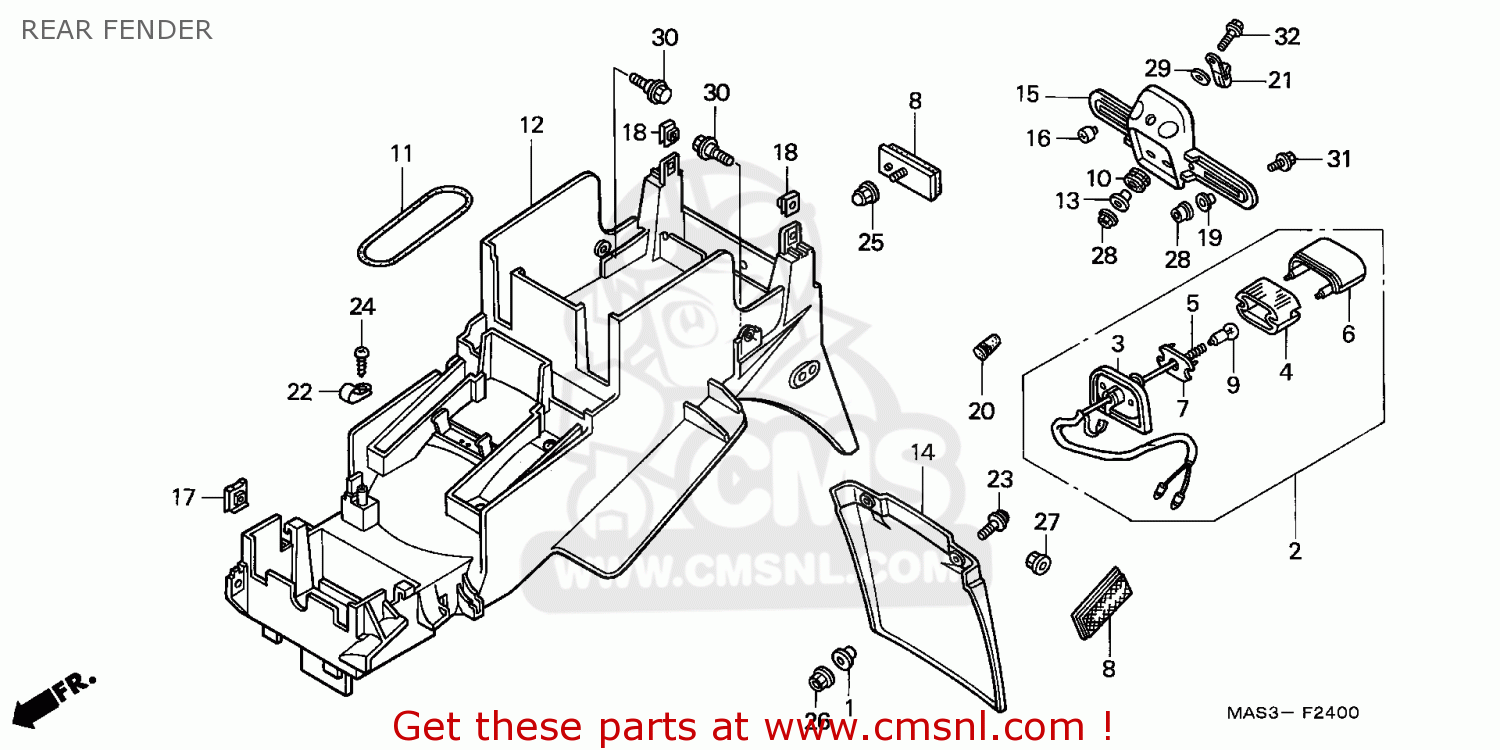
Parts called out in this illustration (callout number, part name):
2	LIGHT ASSY.,LICEN
3	BASE COMP.
4	LENS LICENSE
5	WIRE, LICENSE LIGHT
6	COVER LICENSE
7	PACKING.LENS
8	REFLECTOR,REFLEX
9	BULB
10	RUBBER,FR-FEND.MT
11	BAND,FR NO PLATE
12	FENDER,REAR
13	COLLAR,RR.FENDER
15	BRKT,NUMBER PLATE
16	NUT,SPECIAL,6MM
17	NUT,CLIP,6MM
18	NUT,CLIP,6MM
19	WASHER,6X20.
20	PLUG,CORN
21	CLIP
22	CLIP WIRE HARN
24	SCREW,TAPPING,(PO)4X
25	NUT,HEX,CAP,5MM
27	NUT,FLANGE,5MM
29	WASHER,PLAIN,6MM
30	BOLT,FLANGE,SH,6X25
31	BOLT,FLANGE 6X16
32	BOLT,FLANGE,6X25
